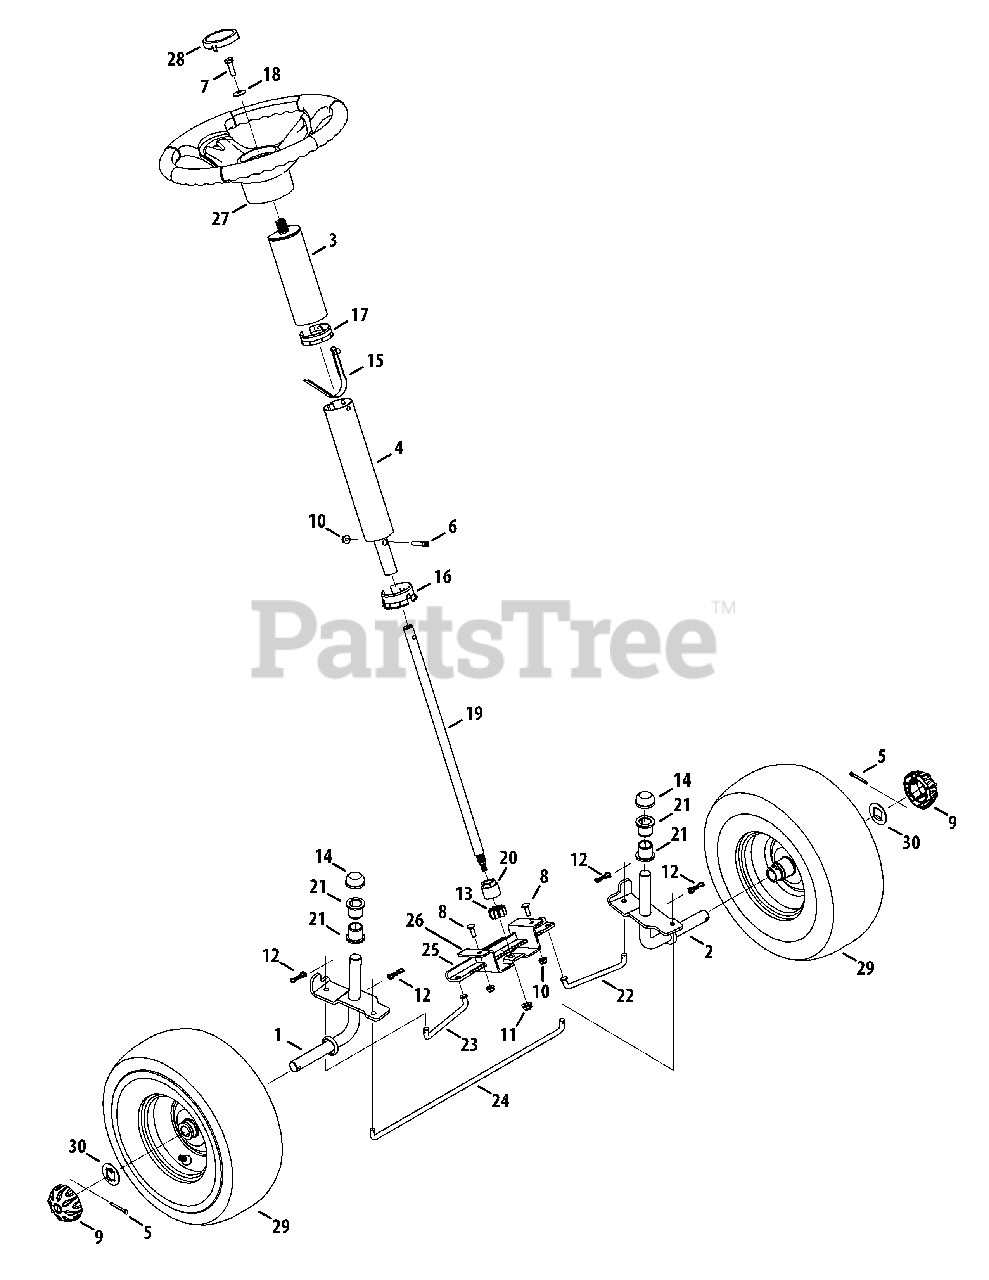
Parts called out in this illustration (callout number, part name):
1	Front Axle Assembly, RH
2	Front Axle Assembly, LH
3	Upper Tube Assembly
4	Lower Tube Assembly
5	Cotter Pin, 5/32 x 1.25
6	Shoulder Screw, .375 x .148 x 1/4-20
7	Hex Head Screw, 5/16-18:1.00
8	Carriage Screw, 1/4-20, .75
9	Hub Cap
10	Flange Lock Nut, 1/4-20
11	Flange Lock Nut, 5/16-18
12	Bow-Tie Cotter Pin, 72
13	Steering Pinion Gear
14	Push Cap, 3/4
16	Lower Steering Collar
17	Upper Steering Collar
18	Bevel Washer, .340X.872X.060
19	Steering Shaft, .625 OD X 18.03
20	Hex Flange Bearing, 5/8
21	Flange Bearing, .760 X .941 X 1.0
22	Steering Rod, LH
23	Steering Rod, RH
24	Front Tie Rod
25	Steering Rack Plate
26	Lower Steering Bearing
27	Steering Wheel, Soft Grip
28	No Sprig Cap
29	Complete Wheel Assembly
30	Washer, .781 x 1.59
